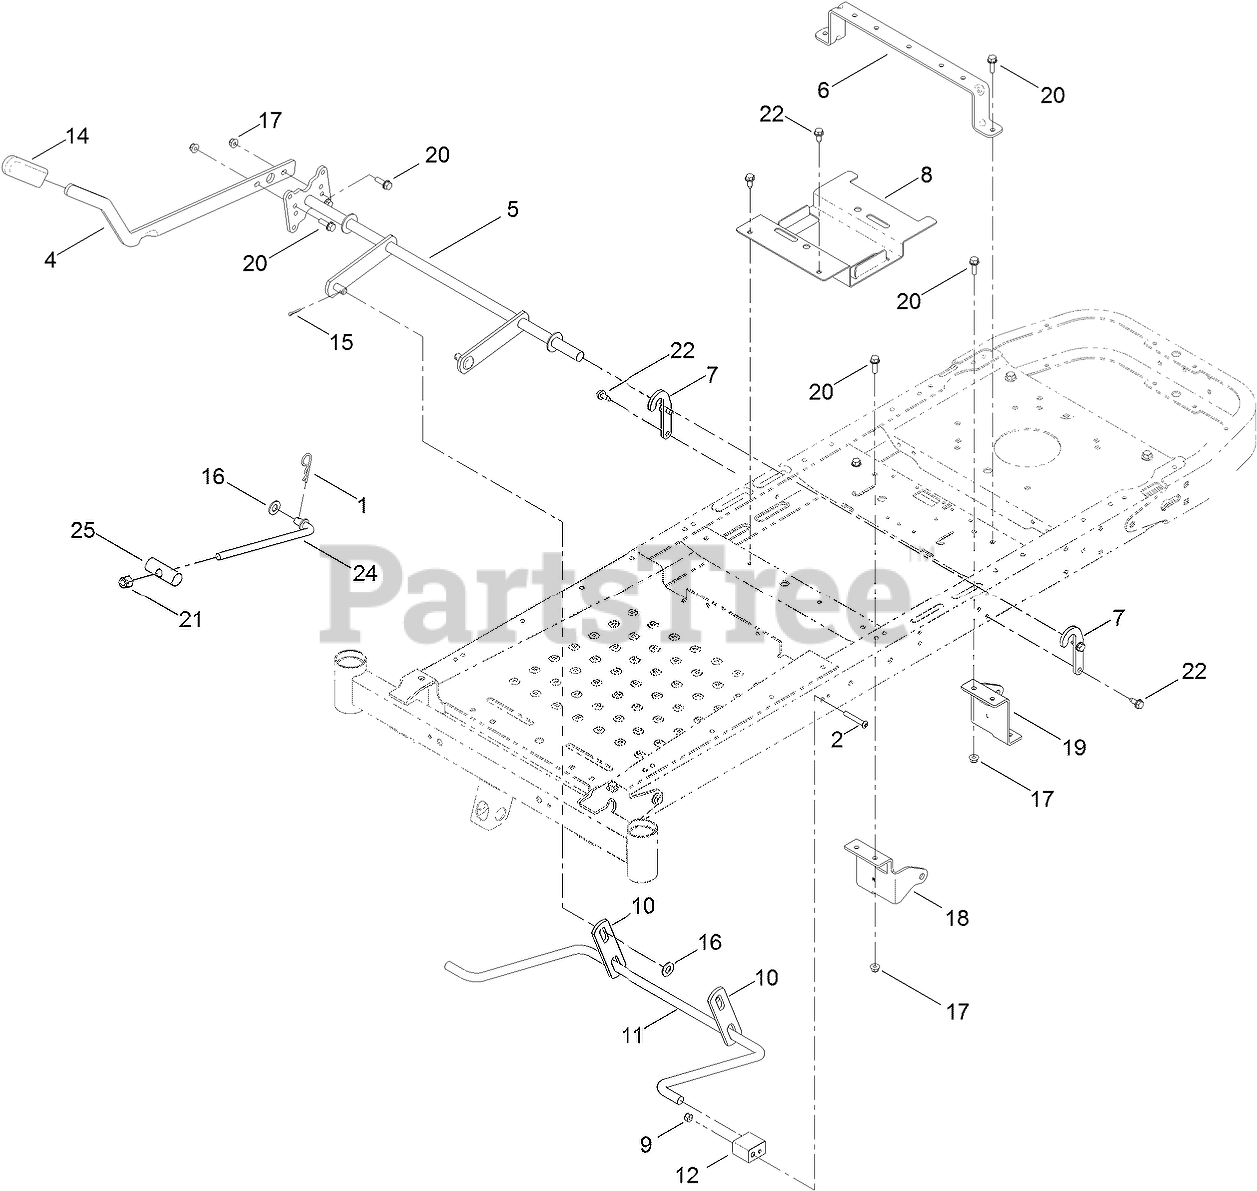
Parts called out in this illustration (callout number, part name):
1	PIN-COTTER
2	SCREW-HSBH
4	LEVER-LIFT
5	LIFT-DECK, NARROW
6	BRACE-SEAT, REAR (NARROW)
7	BRACKET-LIFT
8	BRACKET-BATTERY
9	NUT-LOCK, NI
10	LINK-LIFT
11	ARM-LIFT, REAR
12	BLOCK-PIVOT
14	GRIP-LEVER
15	PIN-COTTER
16	WASHER-FLAT
17	NUT-HF, NI
18	MOUNT-HYDRO, FRONT (RH)
19	MOUNT-HYDRO, FRONT (LH)
20	SCREW-HHF
21	NUT-HEX
22	SCREW-HWHTF
24	ROD-TRUNION
25	PIN-PIVOT
